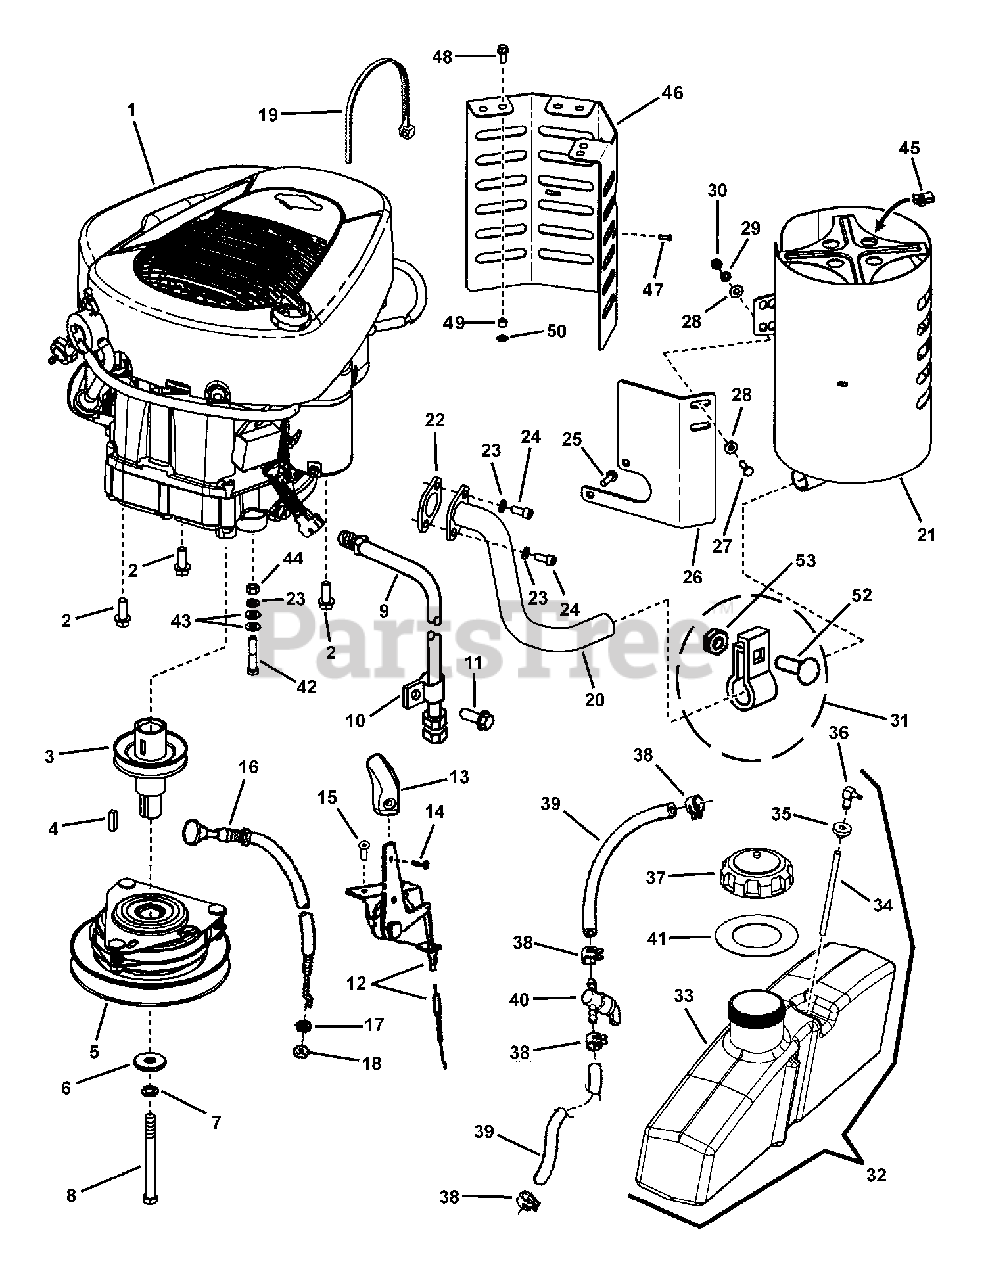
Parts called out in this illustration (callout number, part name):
2	CAPSCREW, Hex Head Flange Taptite, 3/8C X1 BZ
3	PULLEY, Engine
4	KEY, Square, 1/4X1
5	CLUTCH, # 504586, Electric, Ogura JD-11
6	WASHER, .468X1.50X.19 YZ
7	WASHER, Lock, .445X.776X.1 YZ
8	CAPSCREW, Hex Head, 7/16F X4-1/2, GR5 YZ
9	HOSE, Oil Drain .375ID 16.5L
10	CLIP, HARNESS, 5/8
11	CAPSCREW, Hex Head, Whiz Lock, Flange, 5/16C X5/8 GR5 YZ
12	THROTTLE CONTROL, 26.25
13	KNOB, Throttle, Red, RZT
14	CAPSCREW, Pan Head Self-Tapping, Combo, #10-16 X3/4 BZ
15	CAPSCREW, Pan Head Self-Tapping, TORX, 1/4C X5/8 BP
16	CONTROL, Choke, 30
17	WASHER, Lock, Internal Tooth, 3/8 BZ
18	NUT, Hex, 3/8F GR.B BZ
19	CABLE TIE, 7.0
20	MANIFOLD, 18 HP B&S Intek
21	MUFFLER, LC YZ
22	GASKET, Exhaust
23	WASHER, Lock, .32X.58X.08 YZ
24	CAPSCREW, Square Head, 5/16C X3/4 GR8 BZ
25	CAPSCREW, Hex Head Flange Taptite, 1/4C X3/4 ZP
26	BRACKET, Muffler, 18HP B&S
27	CAPSCREW, Hex Head, 1/4C X3/4 GR5 YZ
28	WASHER, .28X.63X.065 YZ
29	WASHER, Lock, .256X.487X.062 ZP
30	NUT, Hex, 1/4C GR5 YZ
31	CLAMP ASSEMBLY, B&S# 223434,93877,93203
32	FUEL TANK ASSEMBLY, RZT
33	FUEL TANK
36	ELBOW, 90 Degree
37	CAP, Fuel, 3-1/2"
38	CLAMP, Fuel Hose
39	HOSE, Fuel 5
40	VALVE, Fuel
42	CAPSCREW, Hex Head, 5/16C X1-3/4 GR5 YZ
43	WASHER, .34X.69X.08 YZ
44	NUT, Hex, 5/16C GR5 YZ
45	NUT, Speed 1/4-20 U TYPE/070/.140 Black
46	HEAT SHIELD, Muffler, ERZT, MY06
47	SCREW, Pan Head Phillips 8-32 X 1/2
48	HFLCS 1/4-20 X 5/8
49	BUSHING, Steel Sleeve .250 ID X .375 OD X .250
50	NUT, Push For .250 DIA THREAD .500 OD Black
52	BOLT, 5/16-18 x 1-1/4" Square Neck Carriage, GR 5
53	NUT, Hex Flange Lock, 5/16C GR5 YZ
